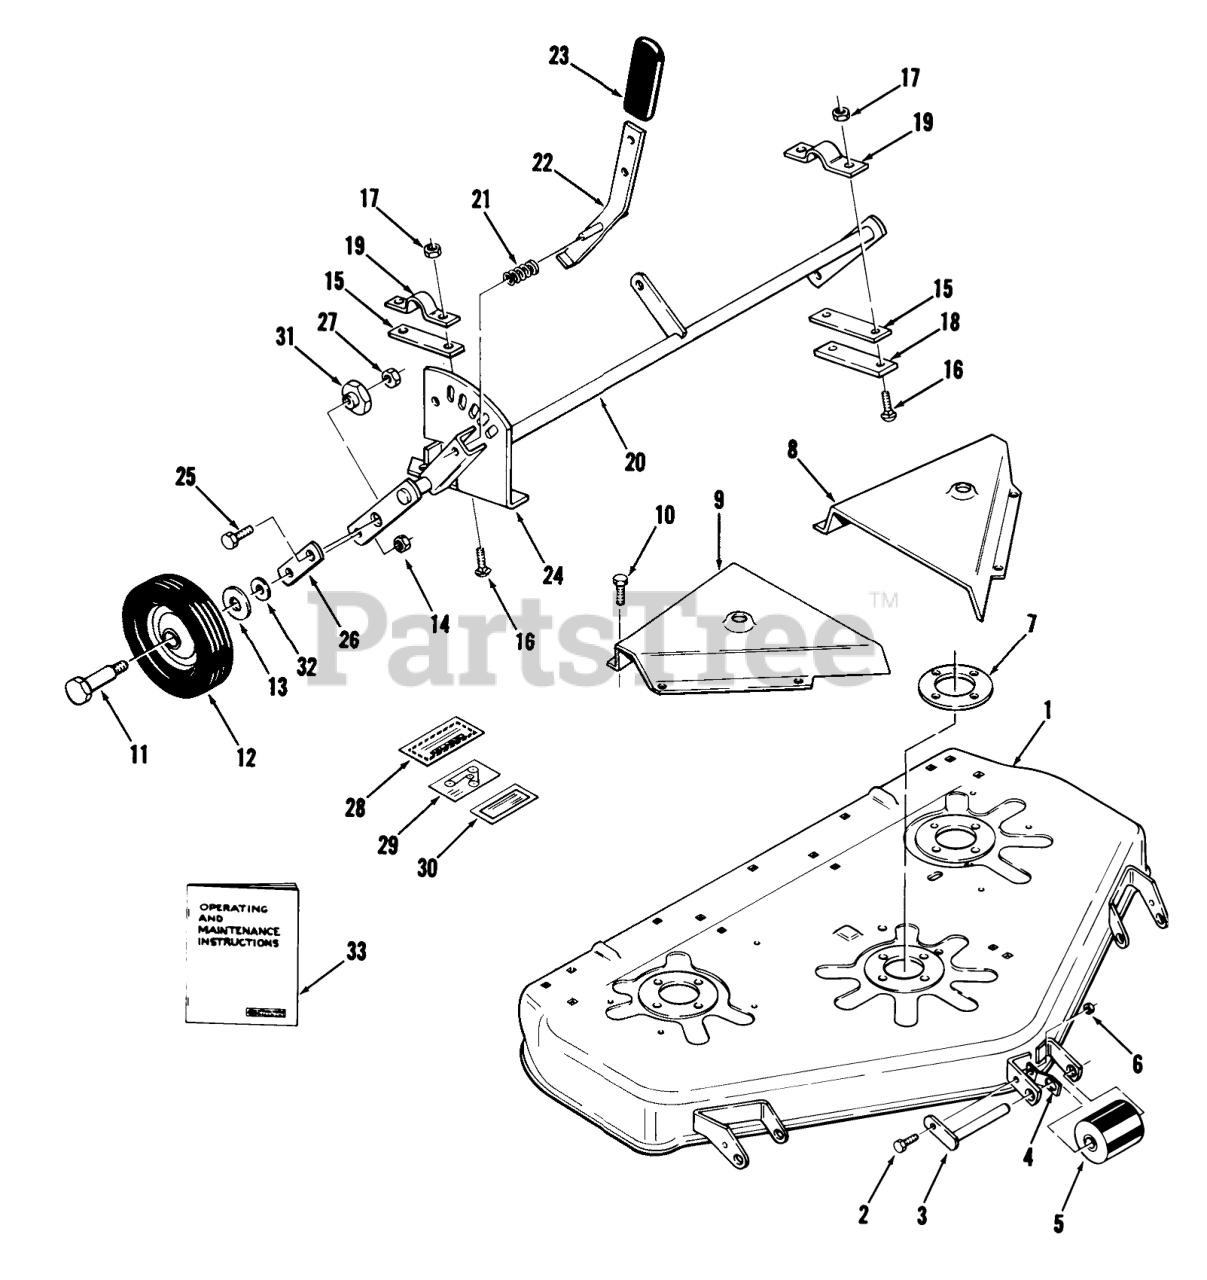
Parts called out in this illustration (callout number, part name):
1	Mower Deck
2	H H C S
3	Roller Shaft
4	SPRING ROLLER STOP
5	Roller
6	Nut
7	PLATE-SPINDLE
8	Belt Cover LH
9	Belt Cover RH
10	Bolt
11	BOLT-SHOULDER
12	Wheel 6 x 1.75
13	WASHER
14	Nut
15	Strap 1/16
16	Bolt
17	Nut
18	Strap
19	CLAMP
20	Gage Wheel Support
21	SPRING-COMPRESSION
22	Lever
24	Quadrant
25	Bolt
26	Wheel Plate
27	Nut
28	Caution Decal
29	DECAL-HEIGHT & BELT
30	Decal-Caution
31	STEERING ARM
32	Washer
33	Operating and Maintenance Instructions
